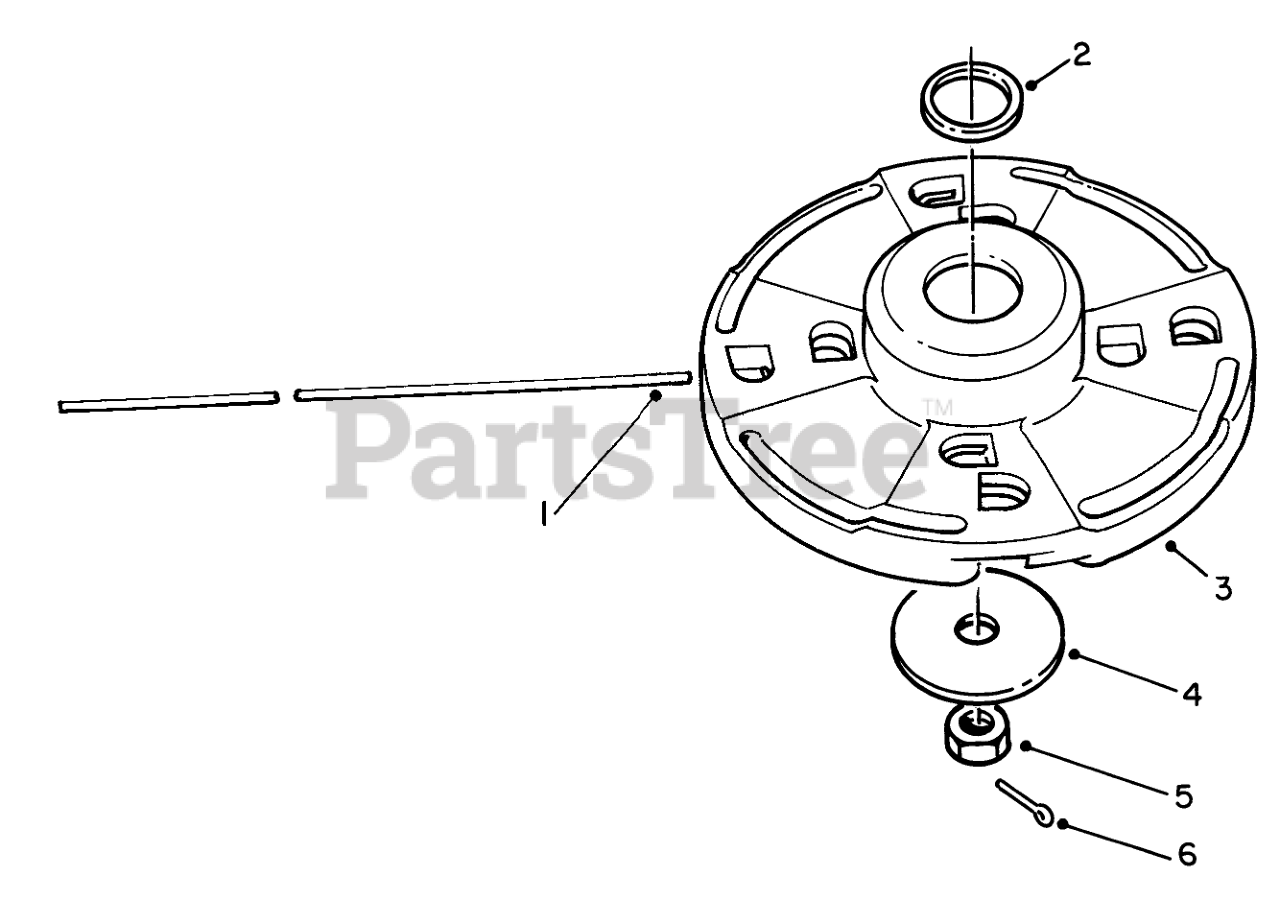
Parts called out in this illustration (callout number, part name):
1	LINE PACK (100)
3	Head Assembly (Incl. Ref. #2)
4	WASHER
6	1/16 X 1 LG COTTER PIN
